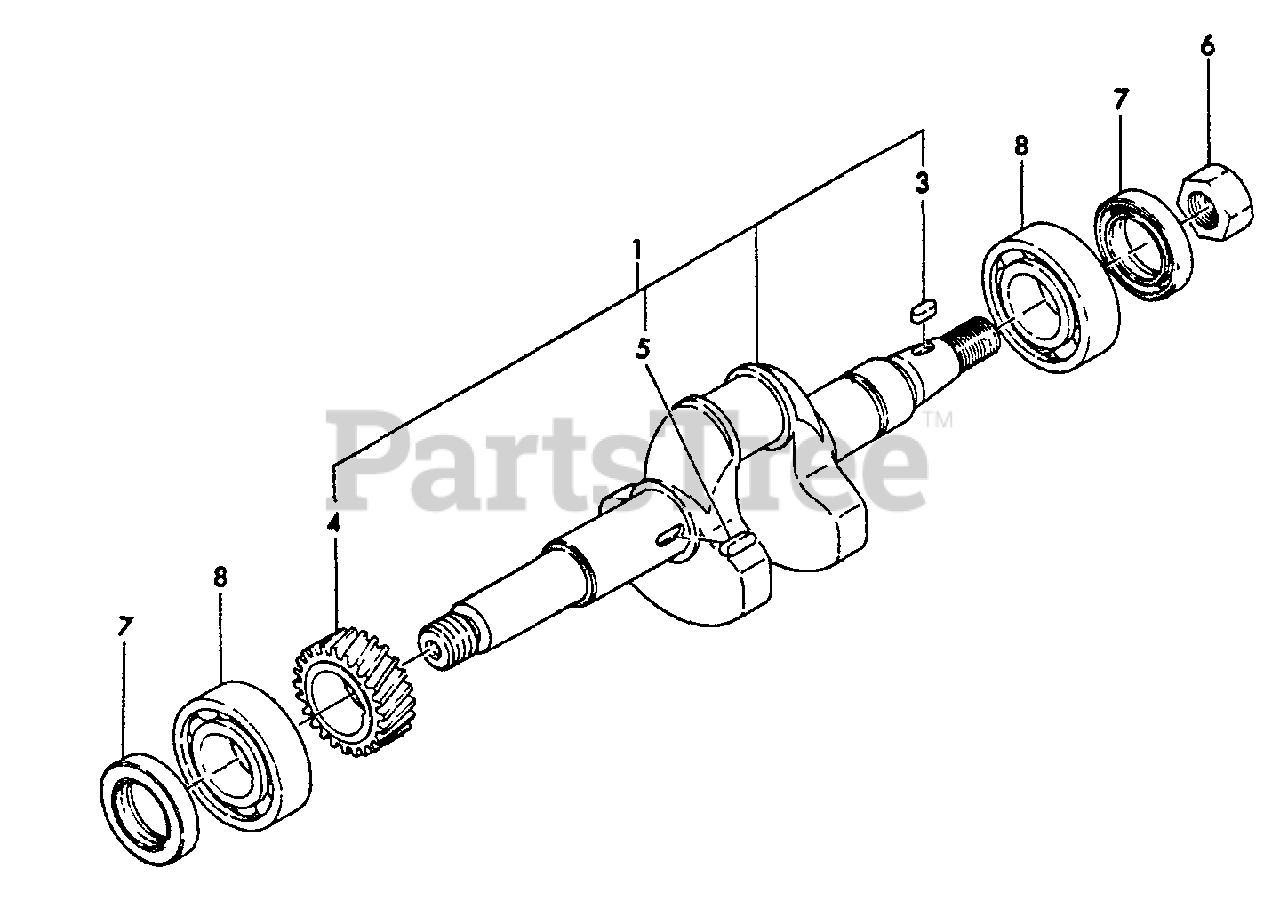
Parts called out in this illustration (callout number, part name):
1	CRANKSHAFT ASSY
3	KEY - 4×10
4	GEAR, CRANKSHAFT
5	KEY 4×12
6	NUT - 14
7	SEAL, OIL
8	BEARING, BALL
